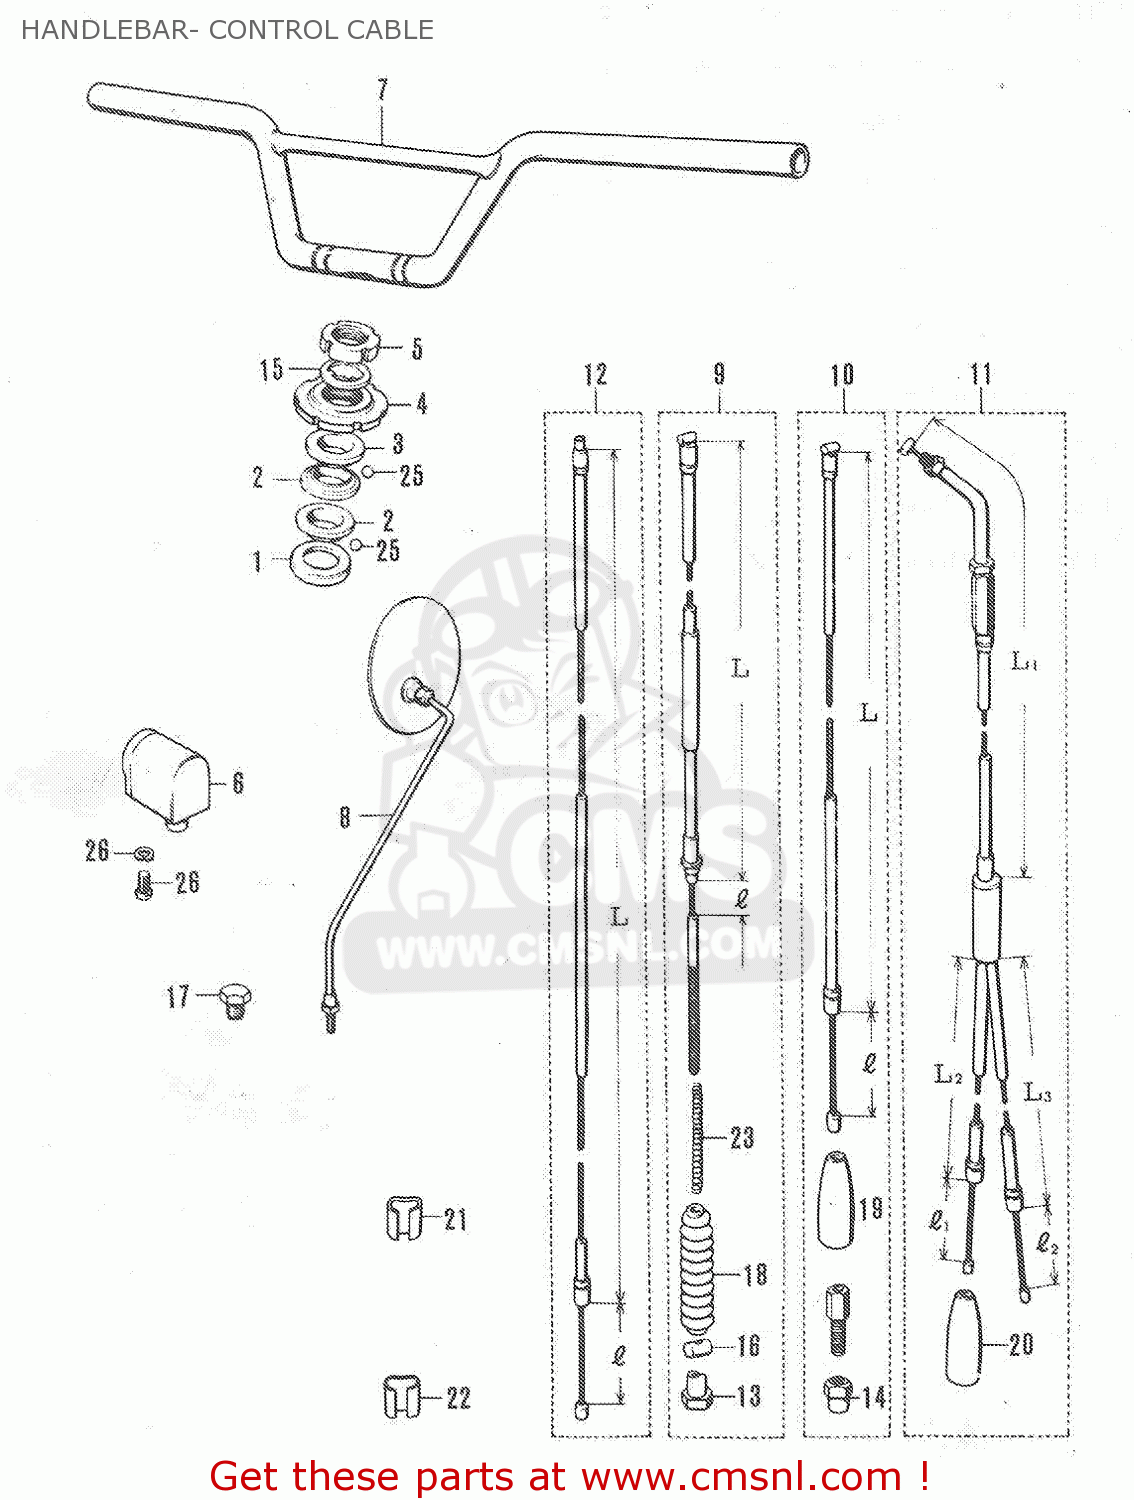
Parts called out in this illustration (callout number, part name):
1	COVER,STEERING STEM
2	RACE,STEERING,INNER,UPPER
3	RACE,STEERING,OUTER,UPPER
4	NUT,STEERING STEM
5	NUT,STEERING STEM
6	LOCK ASSEMBLY,STEERING
7	HANDLEBAR
8	MIRROR ASSEMBLY,REAR VIEW
9	CABLE ASSEMBLY,FRONT BRAKE
10	CABLE ASSY,CLUTCH
11	CABLE ASSEMBLY,THROTTLE
12	CABLE COMP,STARTER
13	NUT
14	NUT
15	WASHER
16	PIN,10X19
17	CAP
18	SEAL,DUST(7X16X75)
19	DUST SEAL
20	DUST SEAL
21	CLIP
22	CLIP
23	SPRING
24	SCREW
25	STEEL BALL
26	LOCK WASHER
